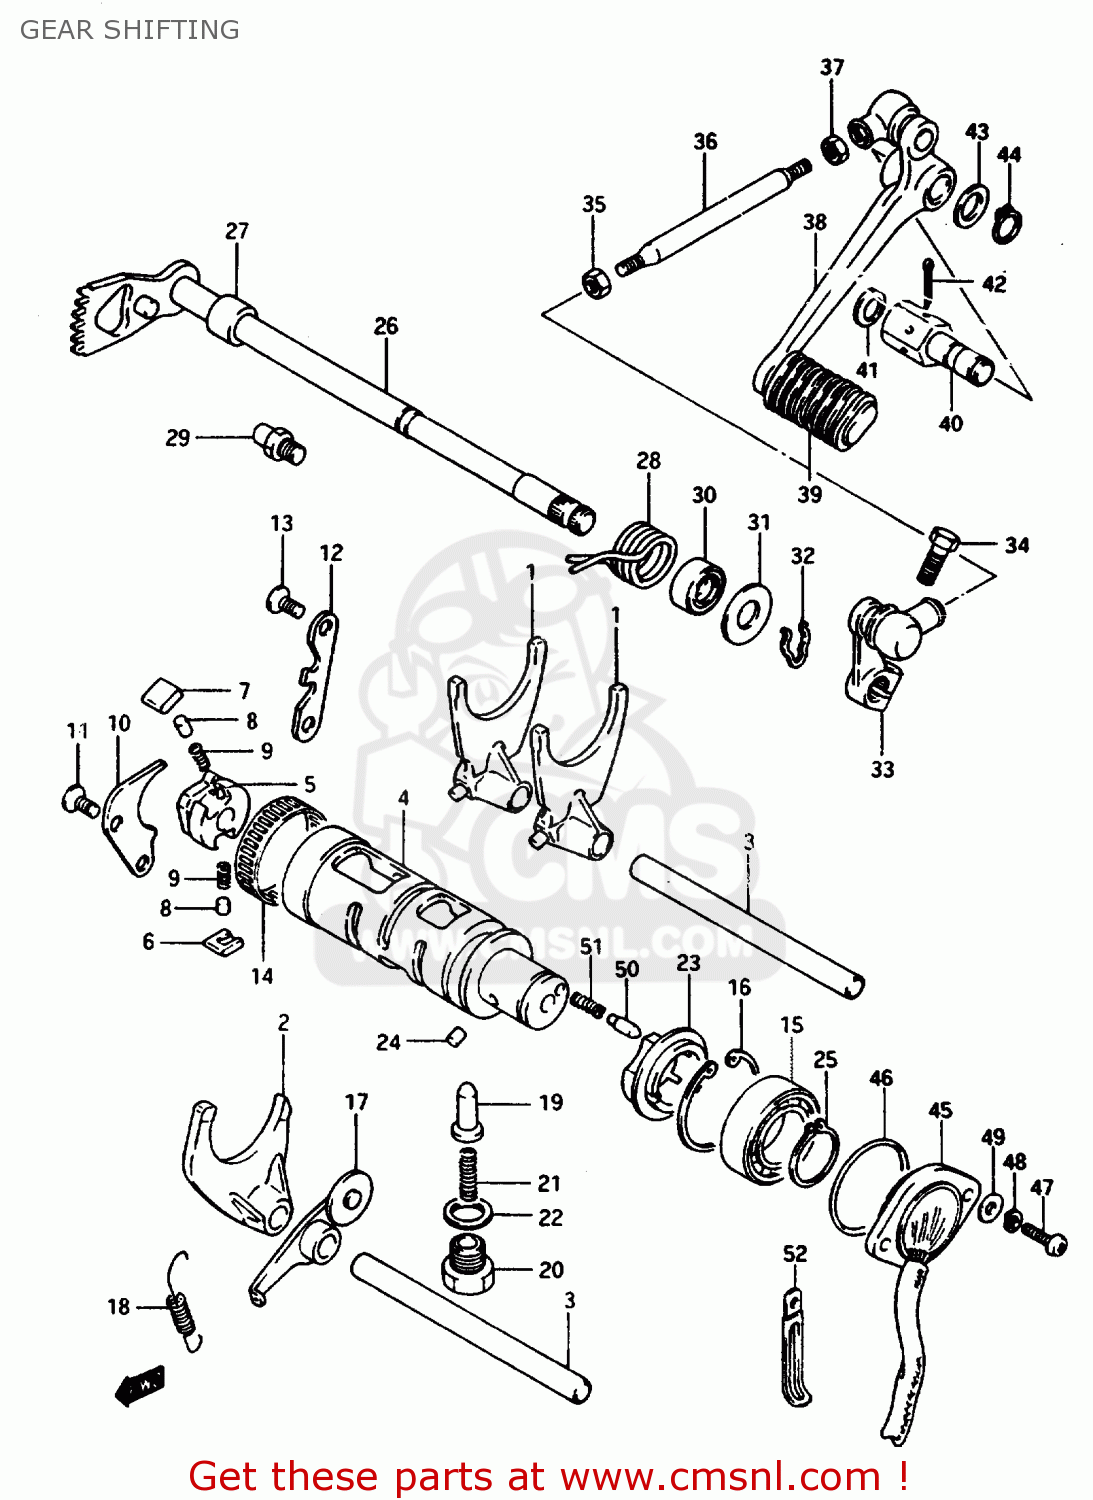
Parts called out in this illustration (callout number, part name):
1	FORK,GEAR SHIFT NO.1
2	FORK,GEAR SHIFT NO.2
3	SHAFT,GEAR SHIFT FORK
4	CAM,GEAR SHIFT
5	GEAR,GEARSHIFT CAM DRIVE
6	PAWL,GEAR SHIFT NO.1
7	PAWL,GEAR SHIFT NO.2
8	PIN(5X8)
9	SPRING
10	LIFTER,GEAR SHIFT PAWL
11	SCREW
12	GUIDE,GEAR SHIFT CAM
13	SCREW
14	BEARING(43X49X12)
15	BALL BEARING
16	CIRCLIP,42MM
17	STOPPER,GEAR SHIFTING CAM
18	SPRING
19	STOPPER,GEAR SHIFT CAM NO.2
20	HOLDER,GEAR SHIFT CAM STOP SPR
21	SPRING
22	GASKET(14X19.2X2) (NAS)
23	PLATE,GEAR SHIFT CAM STOPPER
24	PIN 4X6
25	CIRCLIP,25MM
26	SHAFT,GEAR SHIFT
27	SPACER(12X20X15.3)
28	SPRING
29	STOPPER,GEAR SHIFT CAM
30	OIL SEAL
31	WASHER (12.5X27X1.6)
32	SPRING,RETAINER
33	ARM,GEAR SHIFT LINK
34	BOLT
35	NUT
36	ROD,GEAR SHIFT LINK
37	NUT
38	LEVER ASSEMBLY,GEAR SHIFTING
39	RUBBER,PEDAL
40	SHAFT,GEAR SHIFT LEVER
41	WASHER
42	COTTER PIN
43	WASHER(12.5X20X1)
44	CIRCLIP
45	BASE ASSEMBLY,NEUTRAL SWITCH TERMINAL
46	O RING(D:2.4,ID:36.5)
47	SCREW(5X14)
48	LOCK WASHER
49	WASHER
50	PIN(5X15.5)
51	SPRING
52	CLAMP L:35
